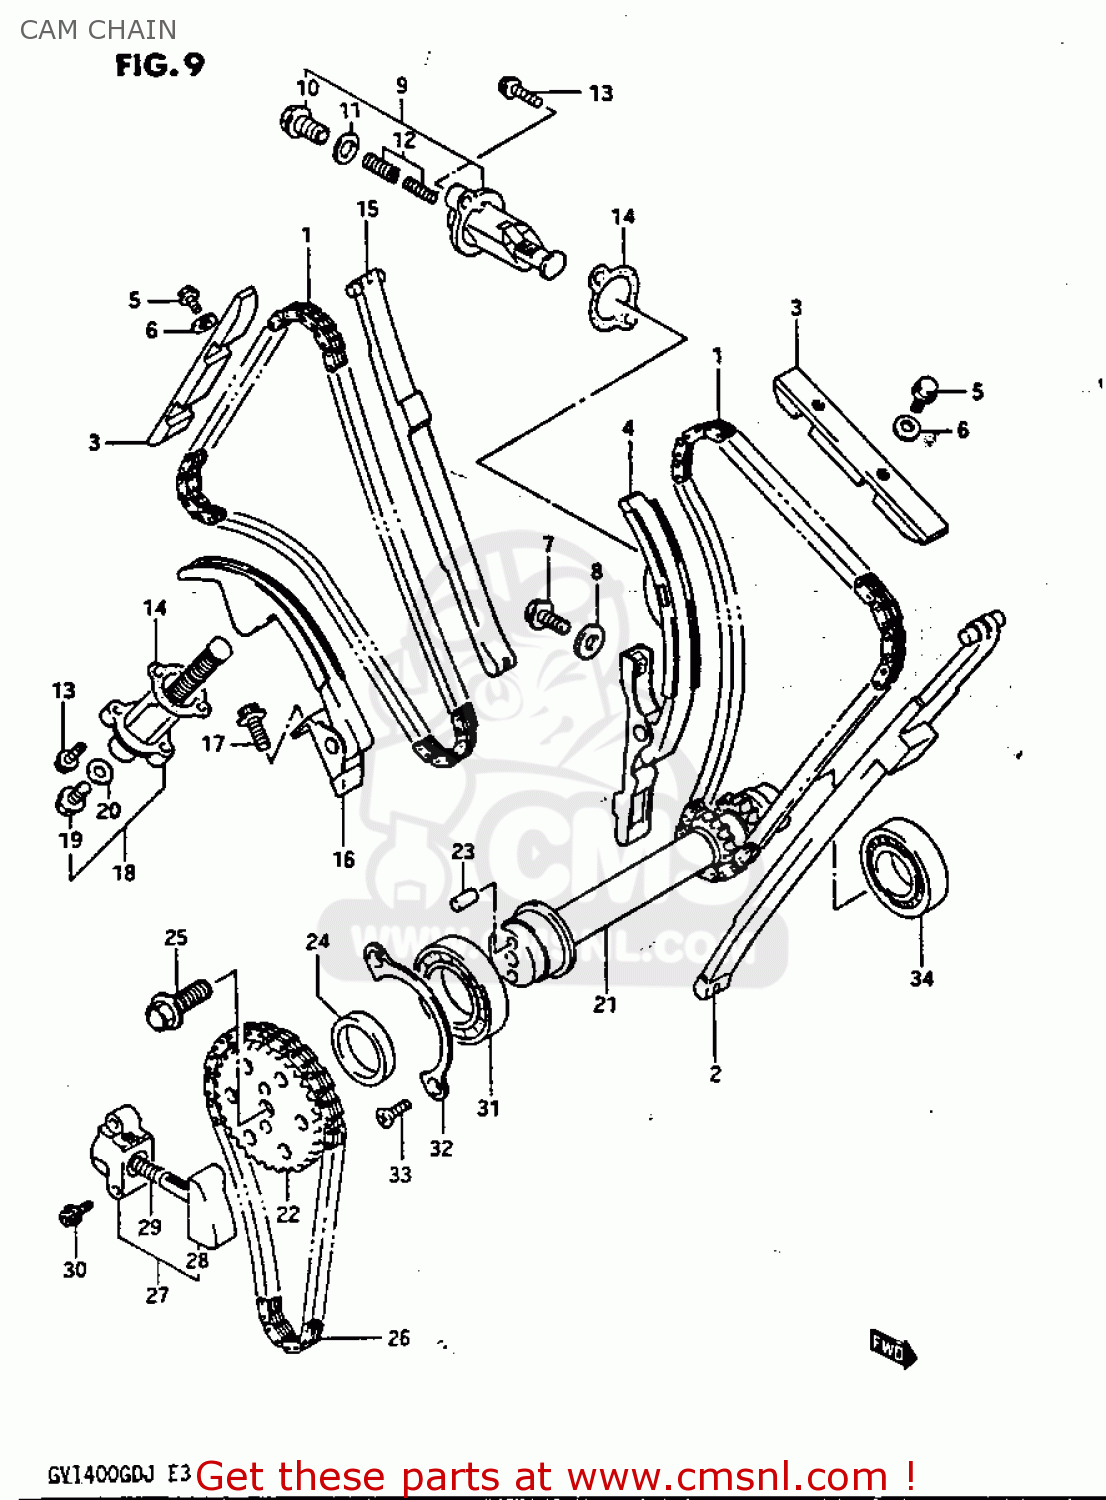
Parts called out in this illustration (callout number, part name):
1	CHAIN COMP,CAMSHAFT DRIVE
2	GUIDE,FRONT CAM CHAIN
3	GUIDE,RR CAM CHAIN NO.1
4	TENSIONER COMP,FRONT CAM
5	BOLT
6	GASKET(5.8X13X1.2) (NAS)
7	BOLT
8	GASKET (NAS)
9	ADJUSTER,FRONT TENSIONER
10	PLUG,FR TENSIONER ADJ
11	GASKET,TENSIONER ADJUSTER (NAS)
12	SPRING SET,FRONT TENSIONER
13	BOLT
14	GASKET,TENSIONER ADJUSTER (NAS)
15	GUIDE,REAR CAM CHAIN N
16	TENSIONER COMP,REAR CAM
17	BOLT
18	ADJUSTER ASSY,RR TENSIONER
19	PLUG
20	GASKET,TENSIONER ADJUSTER (NAS)
21	SHAFT, IDLER
22	SPROCKET,IDLER SHAFT
23	PIN(6X14)
24	SPACER
25	BOLT(10X24)
26	CHAIN,IDLER SHAFT,DRIVE
27	ADJUSTER,IDLE CHAIN
28	BOLT,ADJUST OIL HOSE UNION
29	PLUG,ADJUSTER
30	BOLT
31	BALL BEARING 32X58X13
32	WASHER
33	SCREW
34	ROLLER BEARING (20X47X
